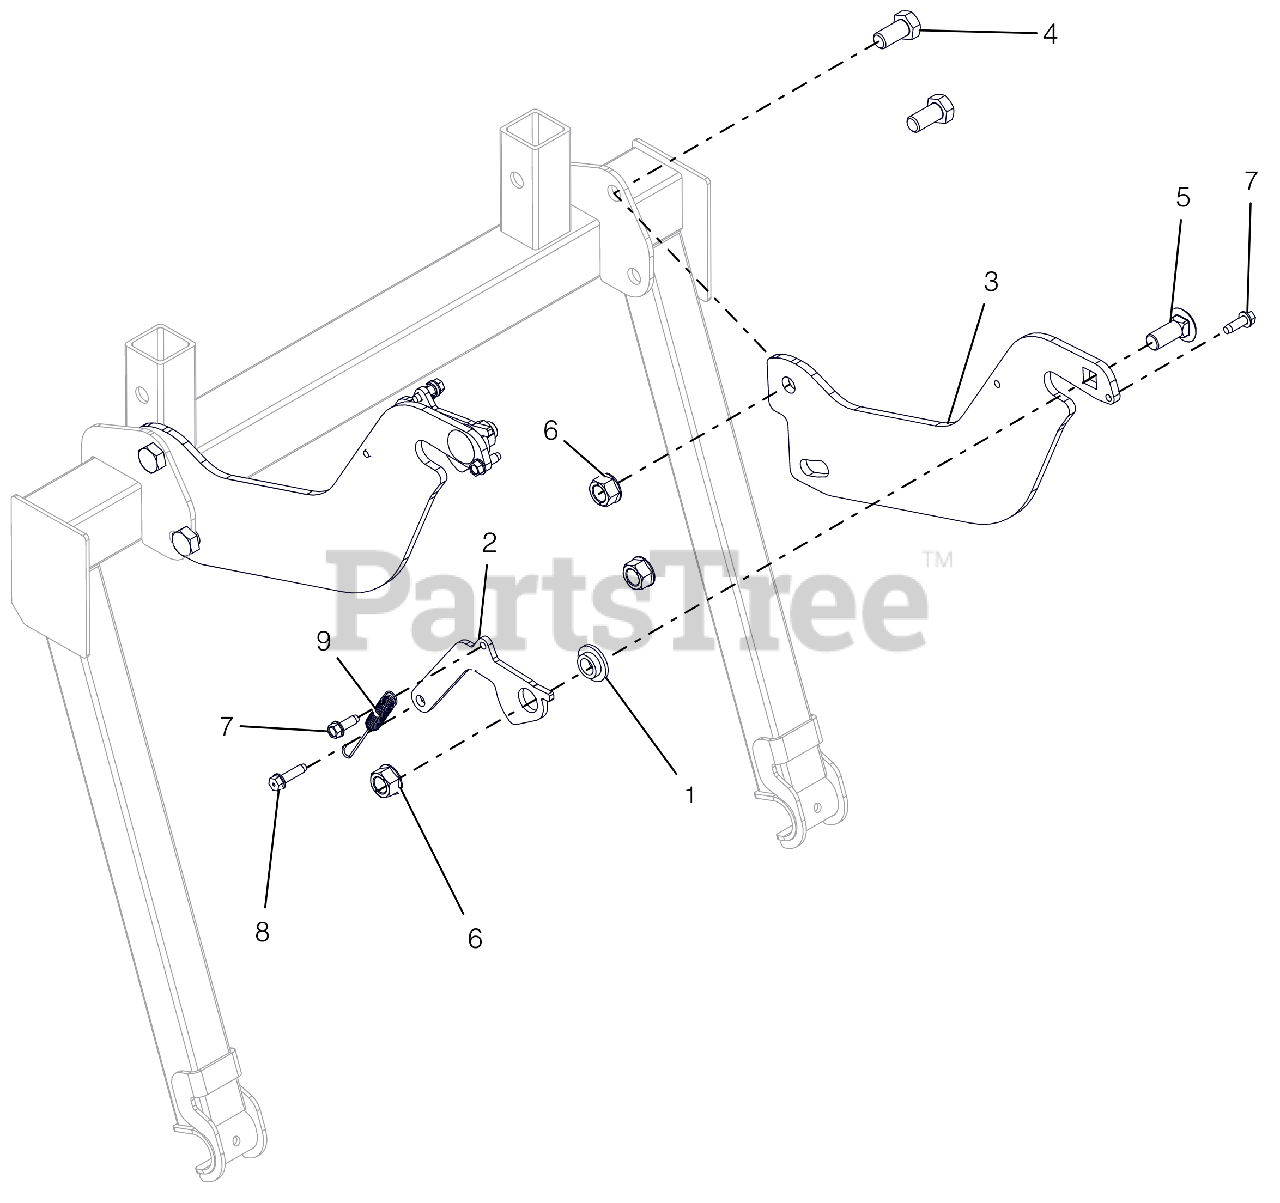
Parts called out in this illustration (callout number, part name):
1	BSHG-FLG .515X.750X.395X1.120
2	BAGGER, LATCH - BLACK
3	LATCH, BAGGER MTG ARMS
4	@BLT-HEX .50-13X1.00 GR5 YWZC
5	@BLT-RDHDSQNK .50-13X1.25 G5YZ
6	@NUT-LK-TOP-FLG .50-13 YWZC
7	SCR-TAP-PM .25-20X.75 TR YWZ
8	@SCR-TAP .25-20X1.00 HWH TR YZ
9	SG-TENS .043X.44X3.31 WLD 5.8
